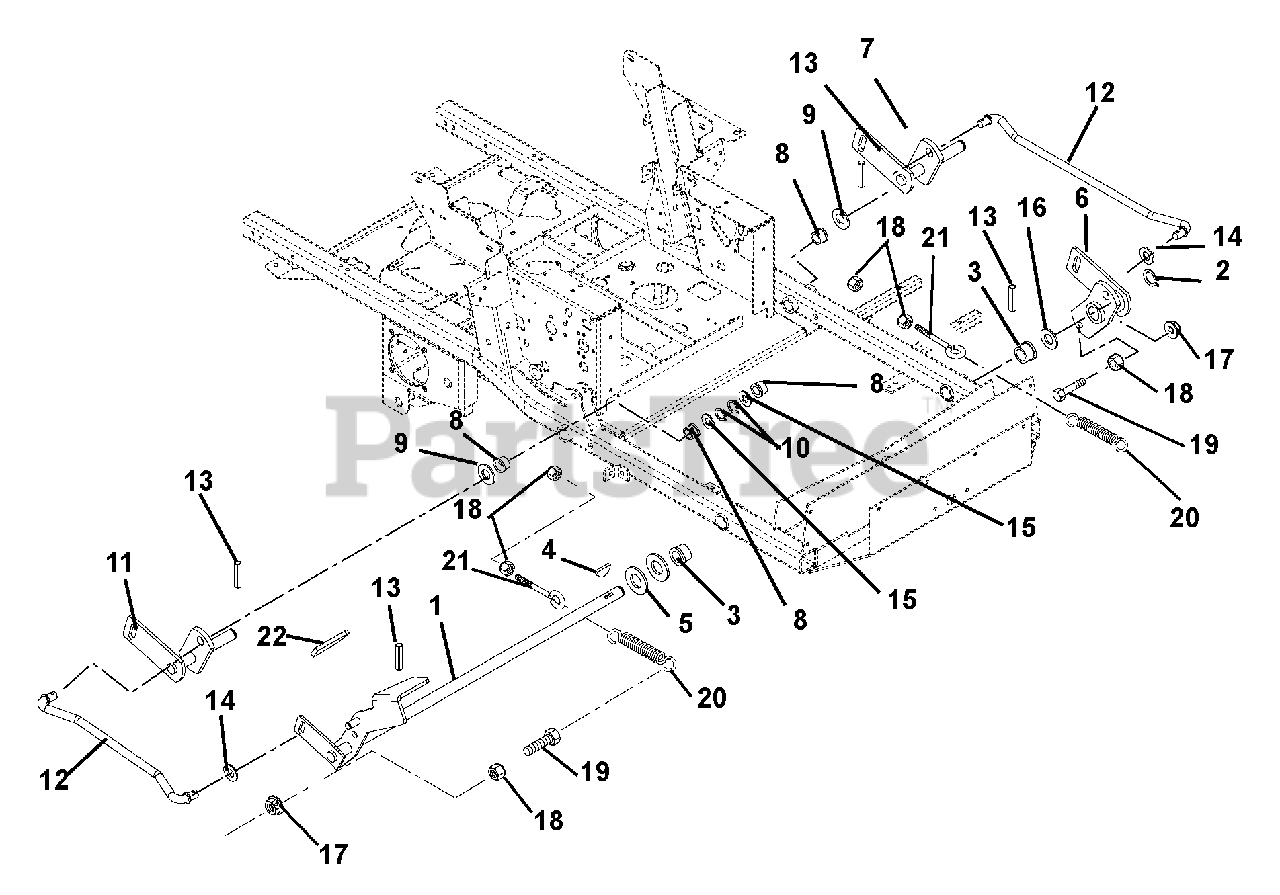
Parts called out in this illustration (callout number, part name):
1	Lift, Mechanical Mower (992111, 113, 115, 117)
1	Lift, Hydraulic Mower (992124, 128, 129, 132, 133, 135, 139)
2	Ring, Retaining External 1.00 x .078
3	Bushing, Flange 1.00 x 1.12 x .75 x 1.375
4	Key, Woodruff .25 x 1.00
5	Washer, Flat Steel 1.062 x 2.00 x .134
6	Weldment, Lift Arm Front
7	Weldment, Lift Arm Shaft Left Hand
8	Bushing, Flange Nylon .762 x 1.00 x .58 x 1.48
9	Washer, Hardened Steel .758 x 1.23 x .031
10	Ring, Retaining External .689 x .077
11	Weldment, Lift Arm Shaft Right Hand
12	Rod, Lift Assist
13	Pin-Roll .250 x 1.25 Stainless Steel
14	Washer-Flat-Steel .630 x 1.25 x .062
15	Washer, Flat Steel .755 x 1.25 x .125
16	Washer, Hardened Thrust 1.00 x 1.55 x .03
17	Nut, Locking-Top-Flange .38-16 992111, 113, 115, 117, 127, 130, 131, 134, 145
18	Nut, Hex .38-16 992111, 113, 115, 117, 127, 130, 131, 134, 145
19	Bolt, Hex .38-16 x 1.75 Grade 5 992111, 113, 115, 117, 127, 130, 131, 134, 145
20	Spring, Tension .162 x 1.25 x 8.25 992111, 113, 115, 117, 127, 130, 131, 134, 145
21	Bolt, Eye .375-16 x 2.50 992111, 113, 115, 117, 127, 130, 131, 134, 145
22	Grip, Foot Pedal
